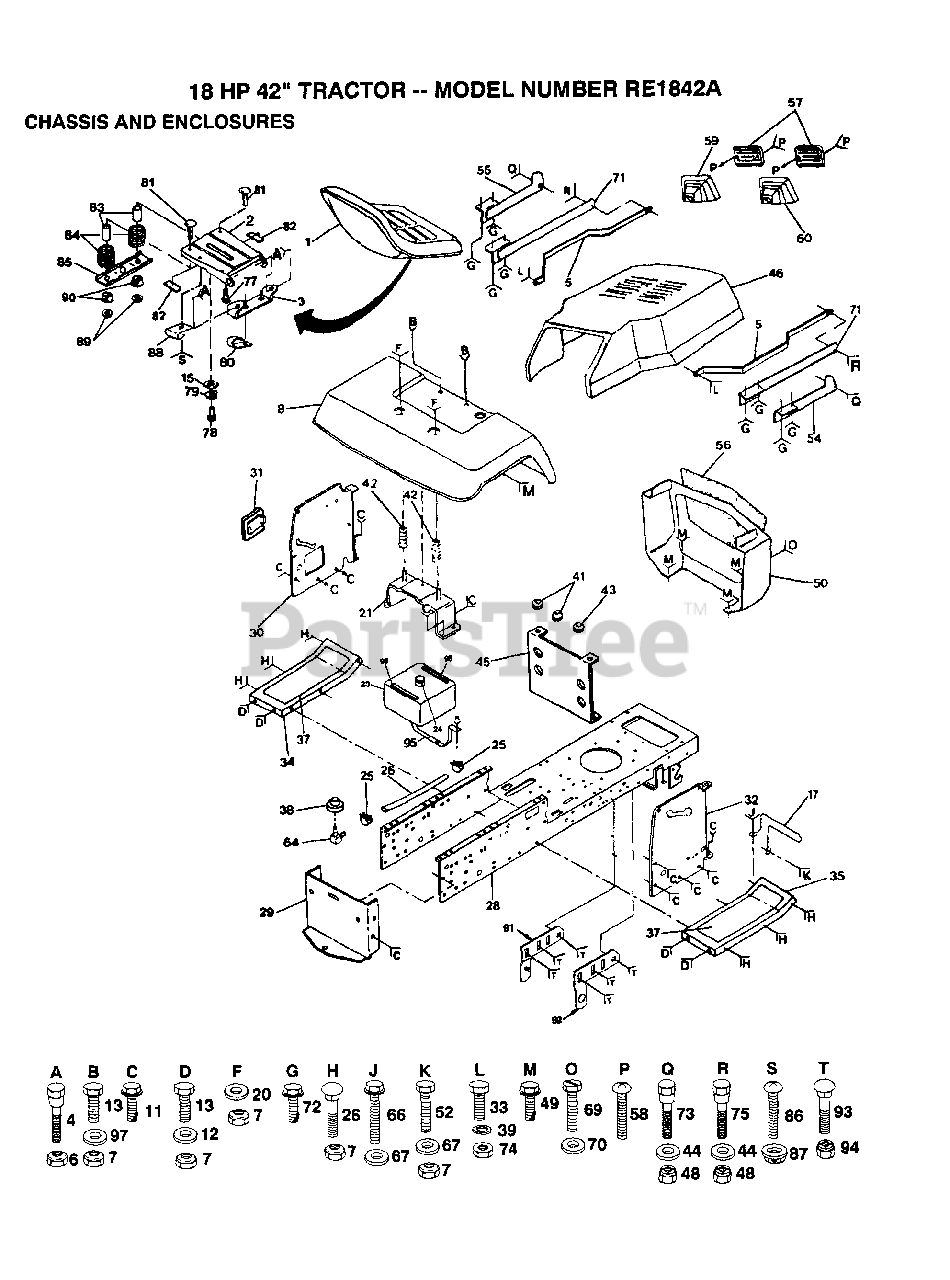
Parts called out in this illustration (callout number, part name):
11	SCREW
12	WASHER
15	WASHER
17	MUFFLER GUARD
20	WASHER
25	HOSE CLAMP
31	COVER ACCESS
33	BOLT LT
36	BOLT
37	"PAD,FOOTREST"
38	BUSHING OUTLET T
39	LOCKWASHER
41	SNAP BUSHING T
42	SPRING COMPRESSIO
49	SCREW LT
54	STRAP ASSY T
55	STRAP ASSY T
56	SCREEN GRILL GTV
63	BOLT
64	FUEL TANK STEM GT
66	SCREW GTV
67	WASHER HYT
69	SCREW
71	STRAP ASSY-REAR T
73	BOLT T
75	"BOLT,SHOULDER"
77	"BOLT,SHOULDER"
78	BOLT
79	LOCKWASHER
80	CLIP T
82	STRIP FORM
83	SPACER SPLIT
84	SPRING COMPRESSED
85	BRKT SWITCH
87	"NUT,KEPS"
90	BUSHING
91	PIVOT BRKT LH
92	PIVOT BRKT RH
93	BOLT
95	"STRAP,TANK"
96	"STRIP,FORM"
97	WASHER
